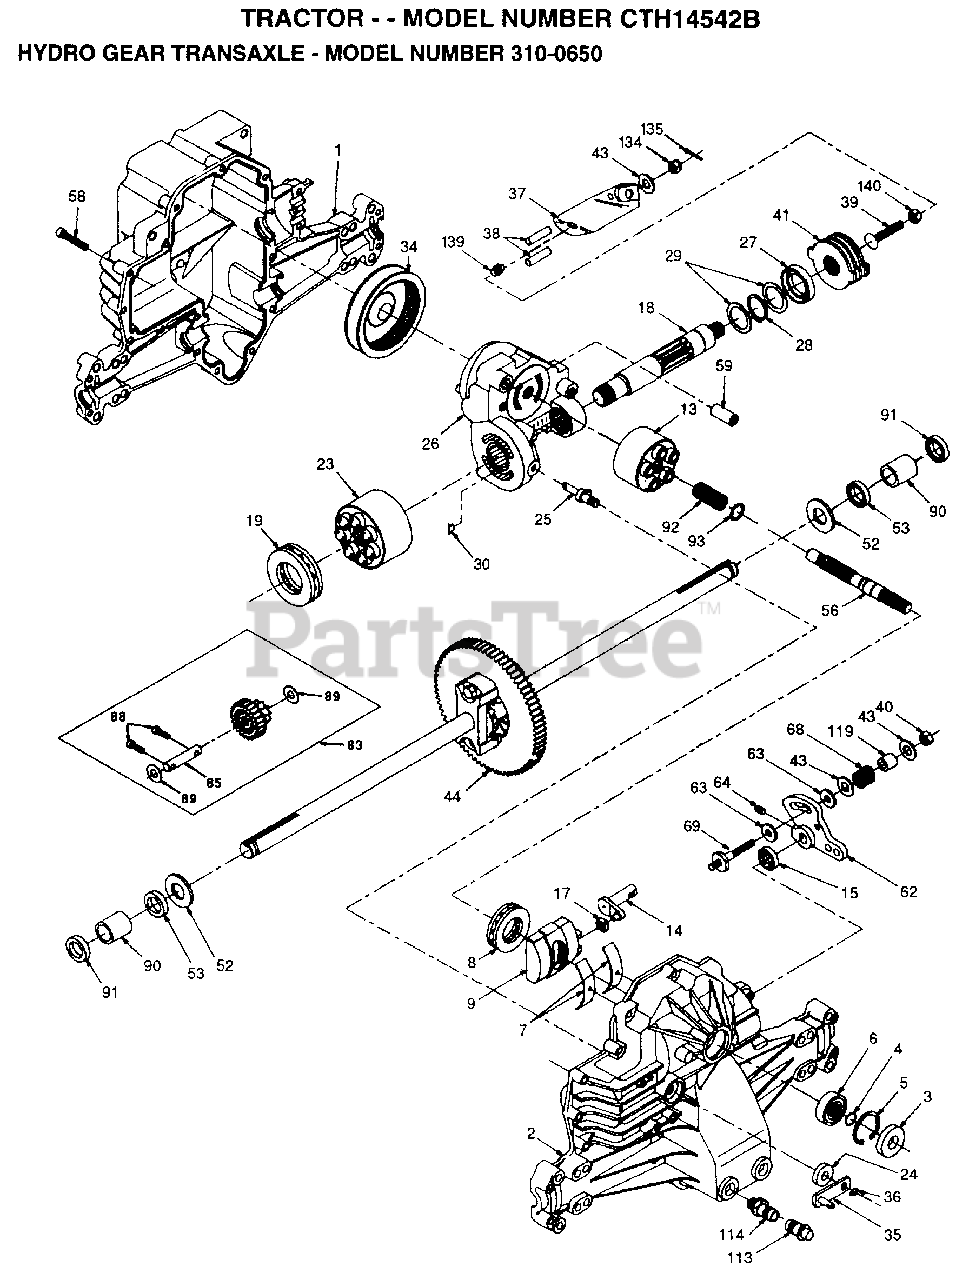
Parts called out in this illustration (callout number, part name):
1	HOUSING.L.50074RM
2	HOUSING.UP.70125
3	SEAL.9008000-0128
4	RING.RET.2003016.
5	RING.RET.2003052.
6	BEARING.(50552)42X68X16
7	CRADLE- 2003023.
8	BEARING.THU.50551
9	SWASHPLT.2003087.
13	BLOCK.CLYN.70079.
14	ARM.TRUN.2003005.
15	SEAL.9008000-0126
17	GUIDE.2000015.
18	SHAFT.MOTOR.50449
19	BEARING.THU.50552
23	BLOCK.CYLIN.70082
24	SEAL.LIP.45074
25	ACTUATOR.2003555
26	KIT.CEN.SEC.70250
27	SEAL.LIP.45075
28	RING RETAIN 50007
29	WASHER.44872
34	ELEMENT.OIL.44964
35	ARM.BYPASS.50270
36	RING.RETAIN.44870
37	ARM.ACTUAT.23710
38	PIN.ACTUAT.44891
39	BOLT.50316
40	NUT.LOCK.HX.50317
41	KIT.BRAKE.70135
43	WASHER HYD 44130
44	DIFFRENTIAL.70226
52	WASHER.HYD.44875
53	SEAL.HYDRO.45076
56	SHAFT.INPUT.50005
58	BOLT.1/4-20.44876
59	PIN.HYDRO.50002
62	ARM.CONTROL.50254
63	PUCK.DAMPER.50281
64	SCREW.SET.50018.
68	SPRING.HYD.50277
69	STUD.5/16-24.DANA
83	JACKSHAFT/PINION GEAR.70132
85	PIN.SHAFT 50559
88	SCREW.CAP.50154.
89	WASHER.HYD.50132
90	BEARING.SLV.50118
91	SEAL.WIPER.50941
92	SPRING.2003014.
93	WASHER.2003017
113	CAP.VENT.70109
114	O-RING.ASM.70110
119	SPACER.HYD.50278
134	NUT.CAS.HYD.44142
135	PIN.COT.HYD.44101
139	SPRING.COMP.50431
140	NUT.HEX.50269
